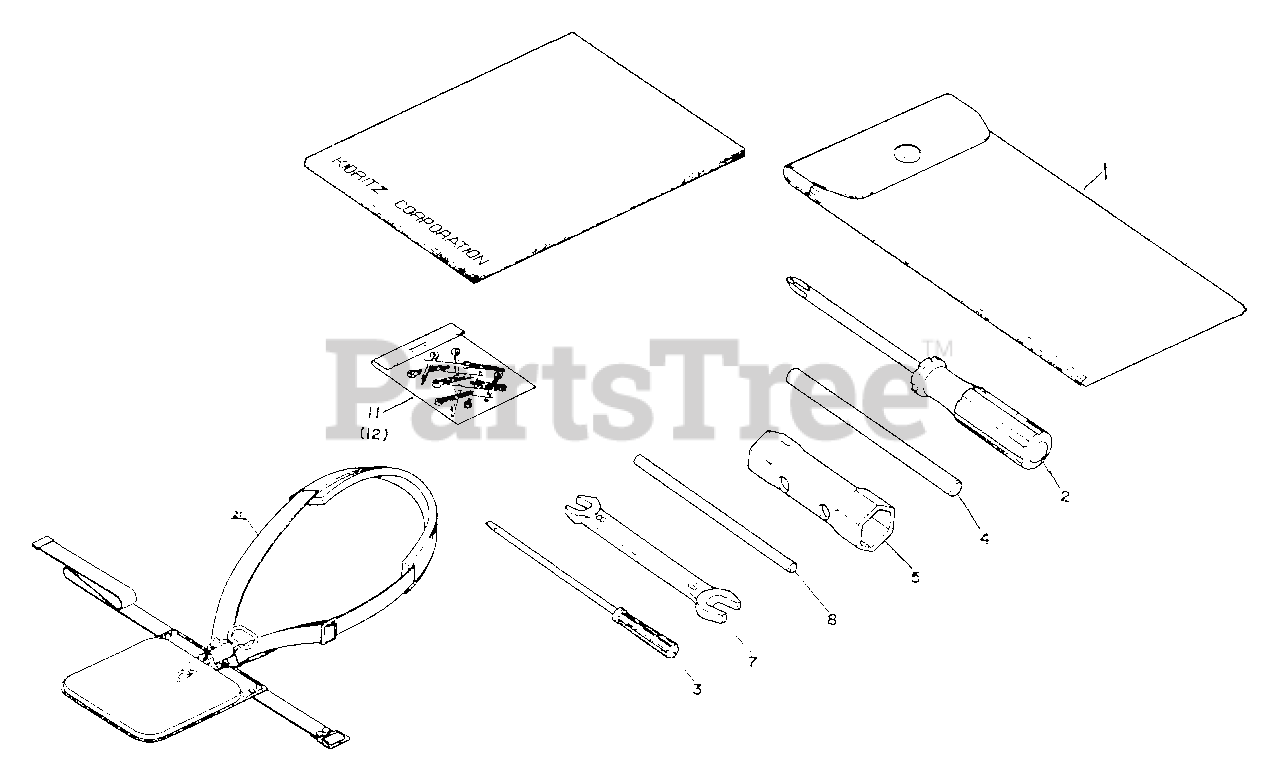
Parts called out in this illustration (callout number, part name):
1	BAG, TOOL
2	SCREWDRIVER - (+)
3	SCREWDRIVER
4	ROD, HANDLE
5	SOCKET WRENCH - 17X19mm
7	SPANNER - 8X10mm
8	LOCKING TOOL
11	PIN, SPLIT - 2X22
13	OWNER'S MANUAL
21	SHOULDER STRAP ASSY
